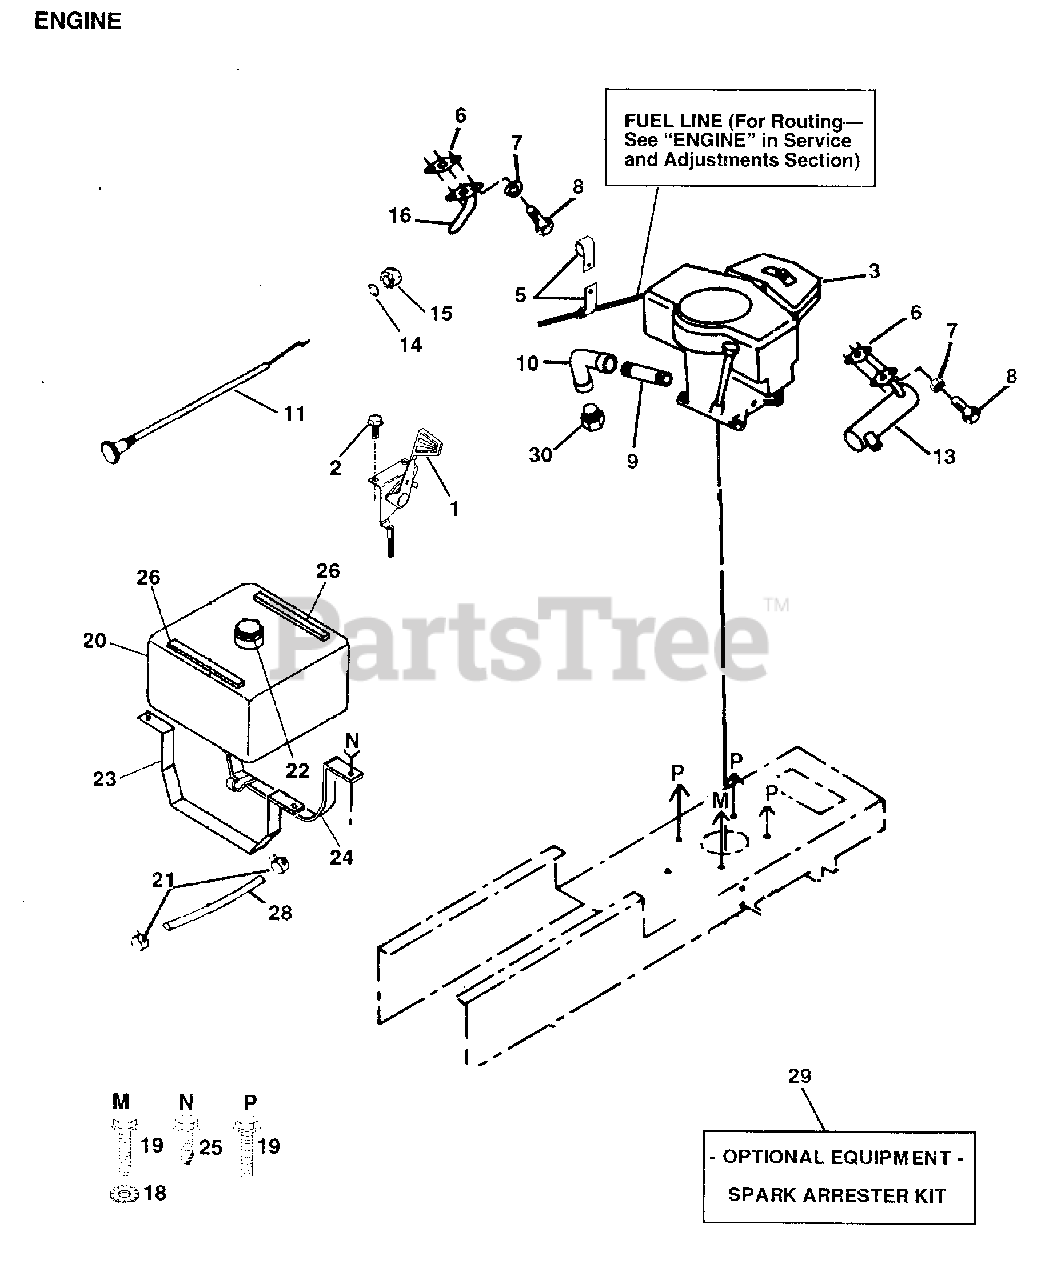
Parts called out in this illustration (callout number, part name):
2	SCREW LT
5	CLIP T
7	LOCKWASHER
9	PIPE NIPPLE LT
10	ELBOW
11	CHOKE CONTROL
14	LOCKWASHER
16	EXHAUST TUBE T
18	LOCKWASHER
19	SCREW
21	HOSE CLAMP
23	"STRAP,TANK"
24	STRAP ASM. F.TANK
25	SCREW LT
26	"STRIP,FORM"
28	HOSE T
29	SPARK ARREST KIT
